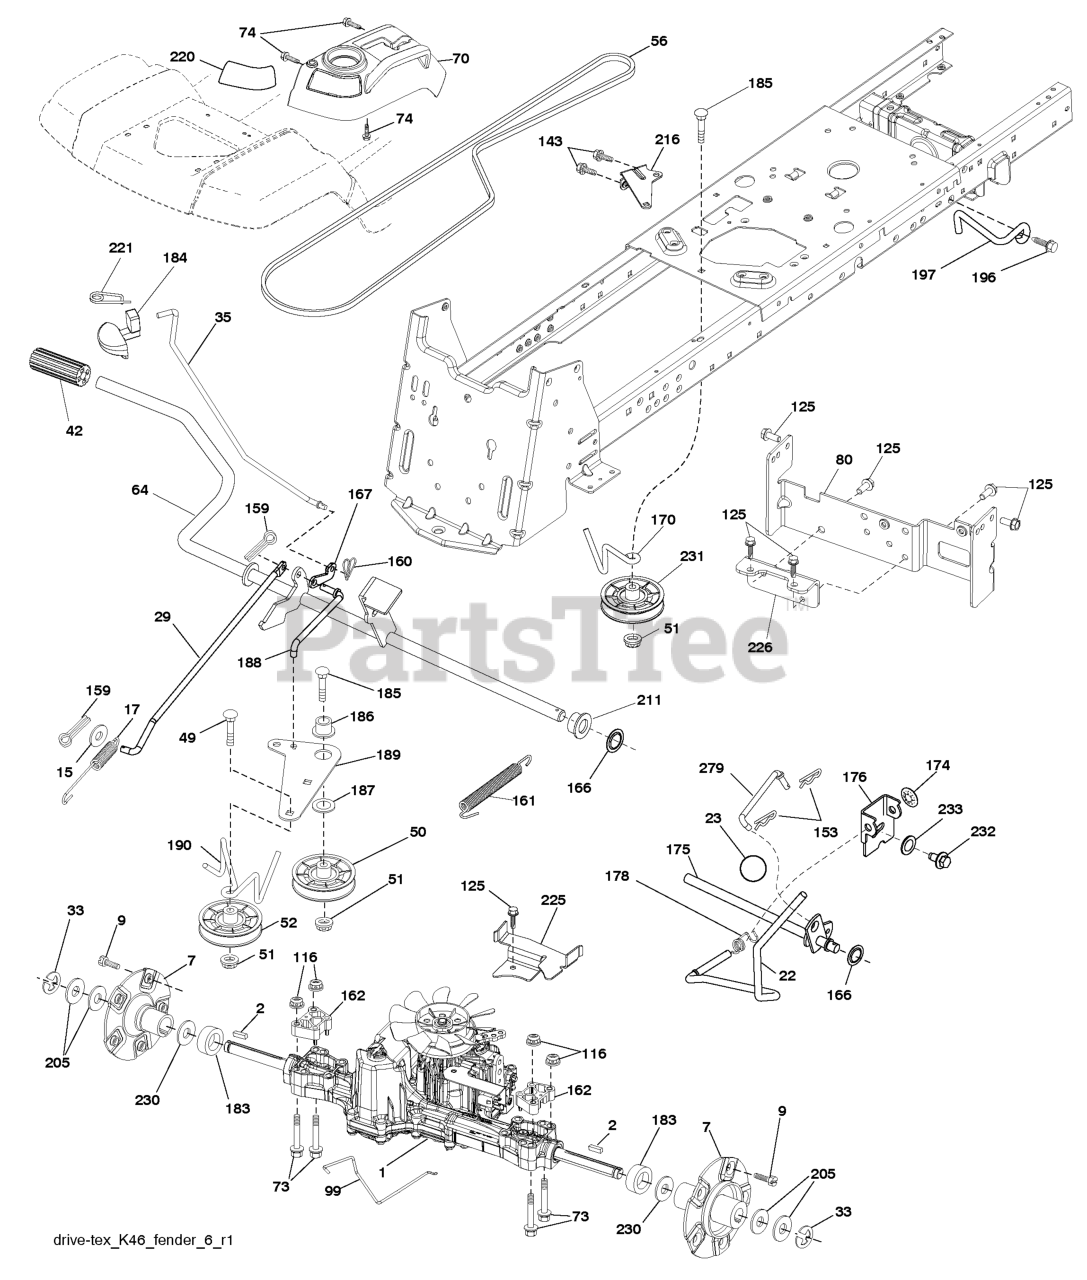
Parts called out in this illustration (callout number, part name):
1	Transaxle, TUFFTORQ K46 AW
2	KEY.SQUARE.187X2.500
7	HUB.ASM.WHEEL.REAR.22"
9	HUB BOLT
15	WASHER
17	SPRING.BRAKE.K46.GREEN
22	ROD.SHIFT.FENDER.STGT.
23	KNOB.DELUXE.(PISTOL.GRIP).BLAC
29	ROD.BRAKE.K46
35	ROD.BRAKE.PARKING.GT.H
42	PEDAL COVER T
49	BOLT
50	IDLER.FLAT.910.OFFSET
51	NUT LOCK FLG 3/8-16 UNC
52	IDLER.V-GROOVE.910.OFFSET
56	V-BELT.MOWER.92.40.42/K46
64	SHAFT.ASM.PEDAL.BRAKE.
70	RP CONSOLE.ASM.HYDO.HUSQ.
73	BOLT.HEX.FLNG.5/16-18X3.75
74	SCREW.HI-LO.CONSOLE
80	STRAP TORQUE
99	ROD.SPRING.BYPASS.K46.TEX.GT
116	NUT LOCK HEX FLANGE 5/16-18
125	SCREW
143	Screw 5/16-18 x 1/2
153	RETAINER M
159	COTTER PIN
160	RETAINER CLIP
161	SPRING, RETURN LT
162	SPACER.TRANSAXLE.18&22
166	NUT.PUSH.625
167	LATCH.BRAKE.SPRING
170	KEEPER.CENTER SPAN.1.688
174	NUT.PUSH.500.2006
175	SHAFT ASM SHIFT
176	ARM.CLEVIS.ROD.SHIFT
178	SPRING.SHIFT.GT2006
183	SPACER.SPLIT.800X.350
184	HANDLE.PARKG.BRK.HUSQ X667
186	SPACER.RETAINER
187	WASHER 12/32X2X10GA
188	RP.LINK.CLUTCH.GROUND.DRIVE
189	BELLCRANK.GROUND.DRIVE.TEX.
190	KEEPER.BELLCRANK.DRIVE
196	SCREW 3/8-16X1
197	BRKT.ANIT-ROTATION.CLUTCH
211	BUSHING.SHAFT.BRAKE.HAND
216	BRACKET.PULLEY.IDLER.W/TEX
220	REFLECTOR.RH.TEX GT
221	RETAINER.SPRING.CLIP.H
225	KEEPER.BELT.TRANSAXLE.K46
226	BRKT.MOUNT.TORQUE.K46.
230	WASHER.HARDENED
231	IDLER.V-GROOVE.1.688.OFFSET
233	WASHER SERRATED
276	BOLT FIN HEX 7/16-14 X 1
279	LINK.SHIFT.T/A.K46.FEND.TX
